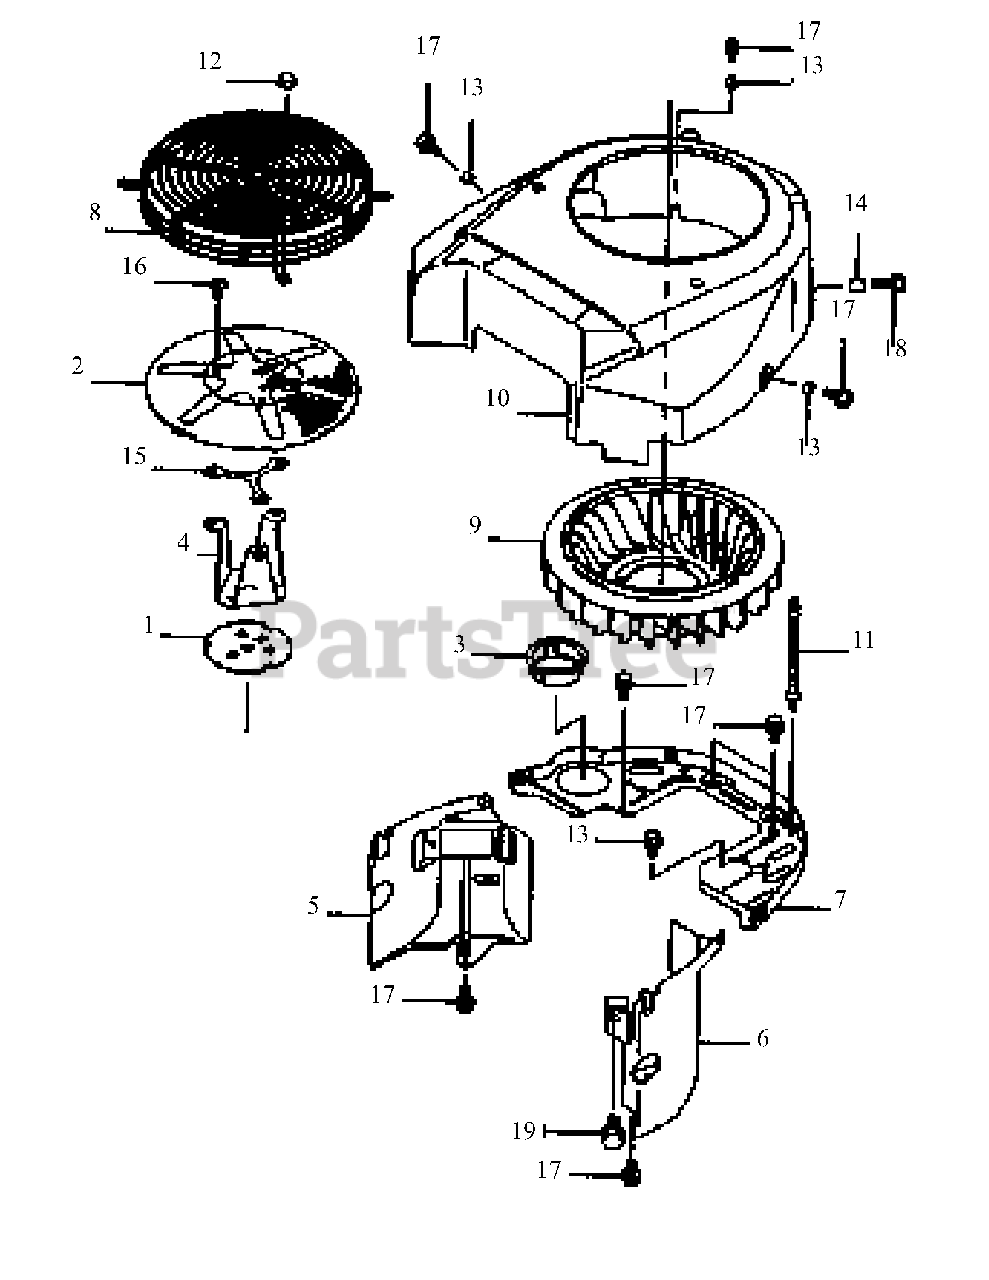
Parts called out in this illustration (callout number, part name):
4	Bracket-Comp
5	Shroud-Engine
6	Shroud-Engine
7	Shroud-Engine
13	Spacer 6.2 x 7.9 x5
14	Spacer6.5x7.9x10.5
16	Bolt, 6 x 10 mm
